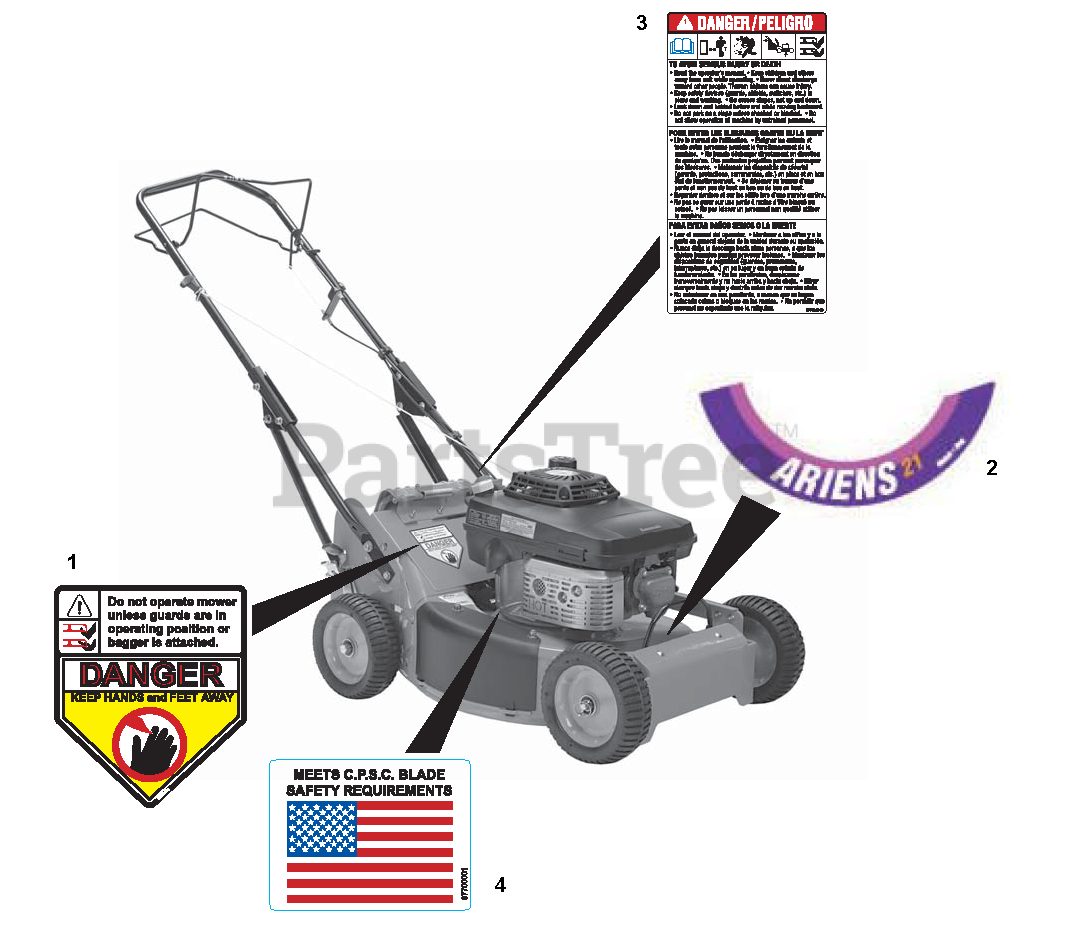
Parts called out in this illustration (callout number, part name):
1	DECAL, CPSC DANGER
2	DECAL, ARIENS DECK (PRO HONDA)
3	DECAL, BILINGUAL DANGER
4	DECAL, CPSC/USA FLAG
